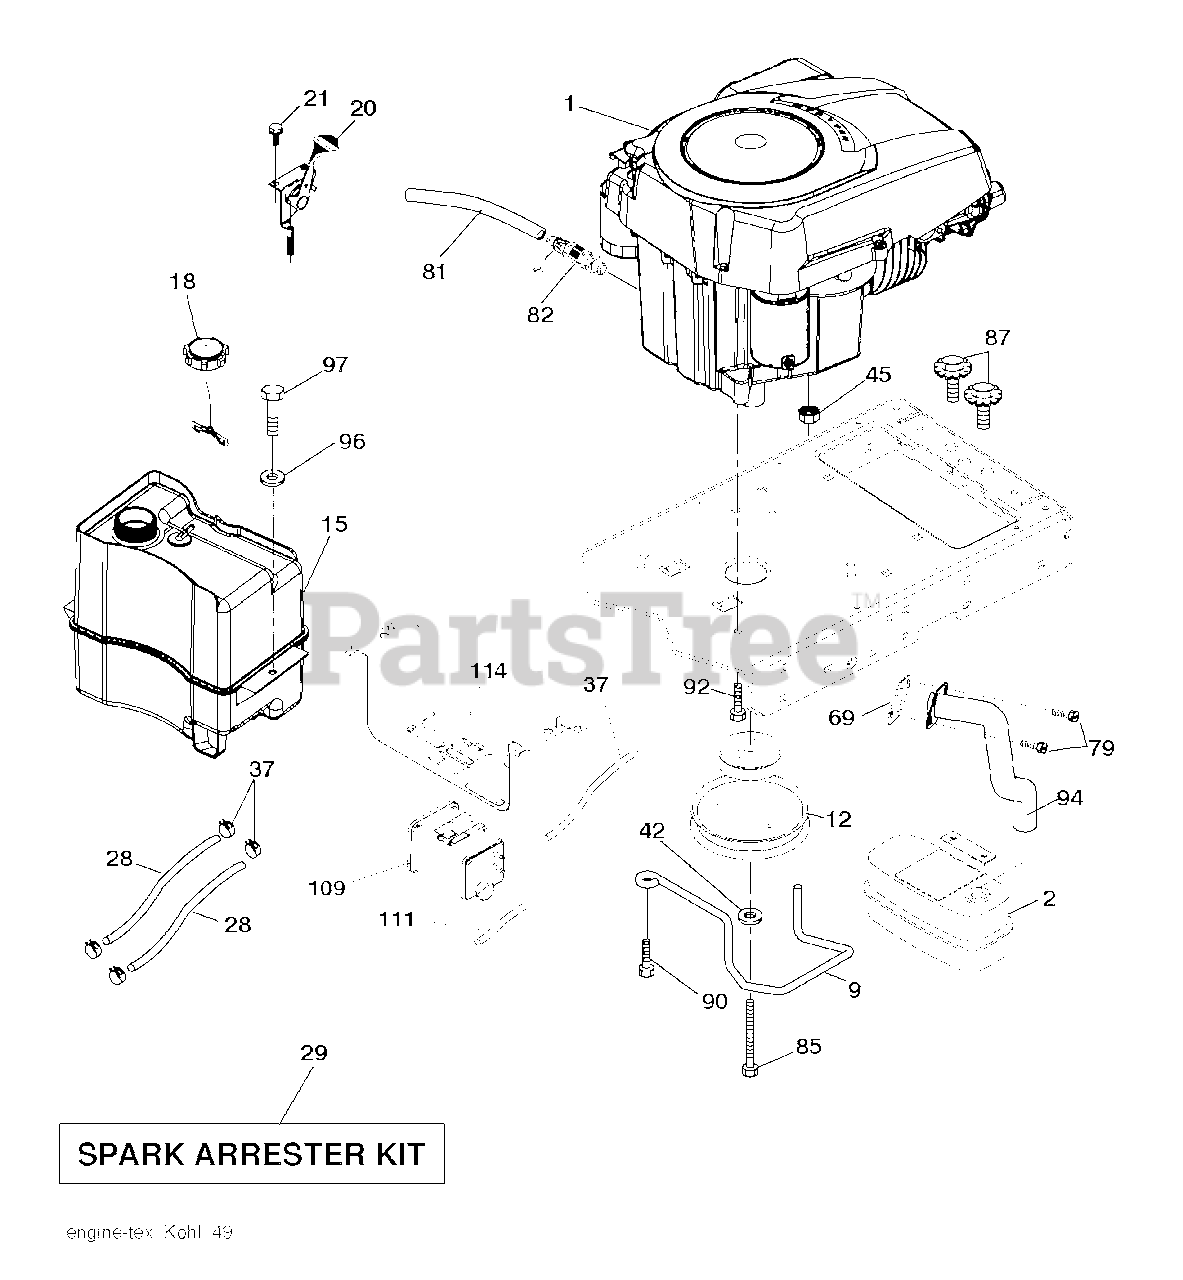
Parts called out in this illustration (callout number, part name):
9	KEEPER.BELT.ENGINE.4.2
21	SCREW.#10 X 0.750.BOS THREAD
29	ARRESTER SPARK (OPTIONAL)
37	HOSE CLAMP
42	LOCKWASHER
79	SCREW.SOCKET HD.5/16-1
81	TUBE, DRAIN OIL ASM.
82	VALUE.OIL.DRAIN
87	BOLT, 5/16-18 X 1 3/4
90	SCREW 3/8-16X1
92	SCREW 3/8-16X1
97	SCREW HEXWSHR 1/4-20X3/4
109	CANNISTER, CARBON
